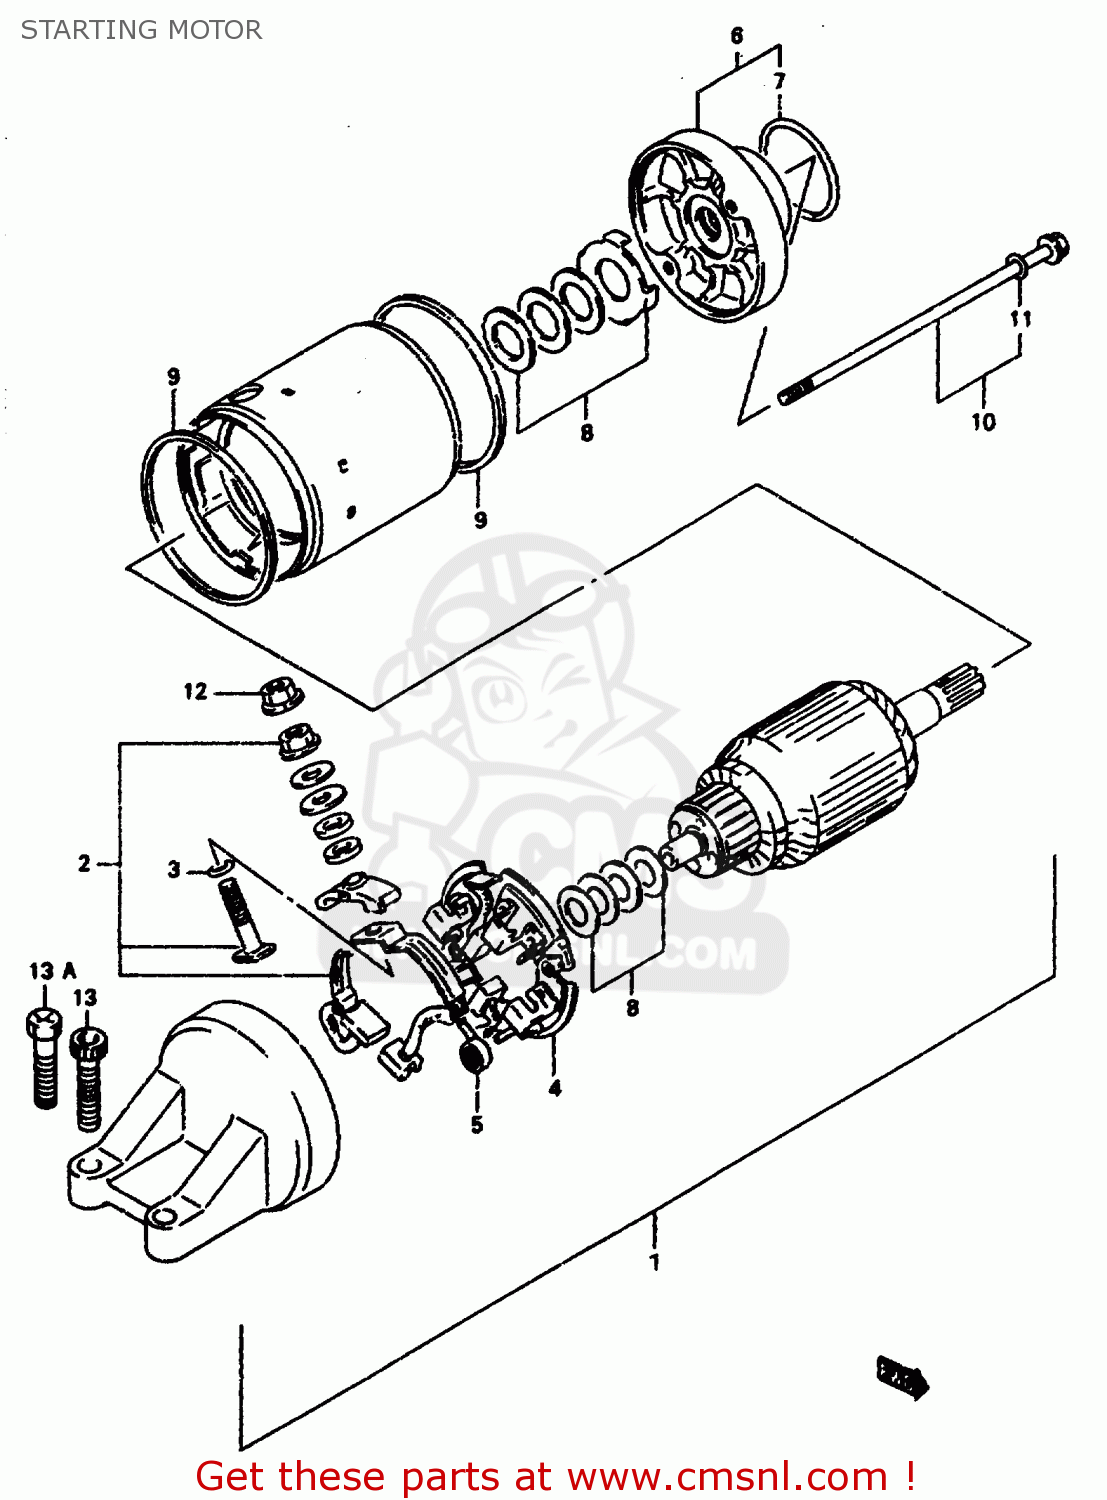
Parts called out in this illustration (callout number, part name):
1	MOTOR ASSEMBLY,STARTING
2	TERMINAL SET, BRUSH
3	O RING
4	HOLDER,BRUSH
5	SPRING
6	HOUSING
7	O-RING
8	SHIM SET,STARTING MOTOR
9	O RING
10	BOLT
11	O RING
12	NUT
13	BOLT
13A	SCREW (6X25)
